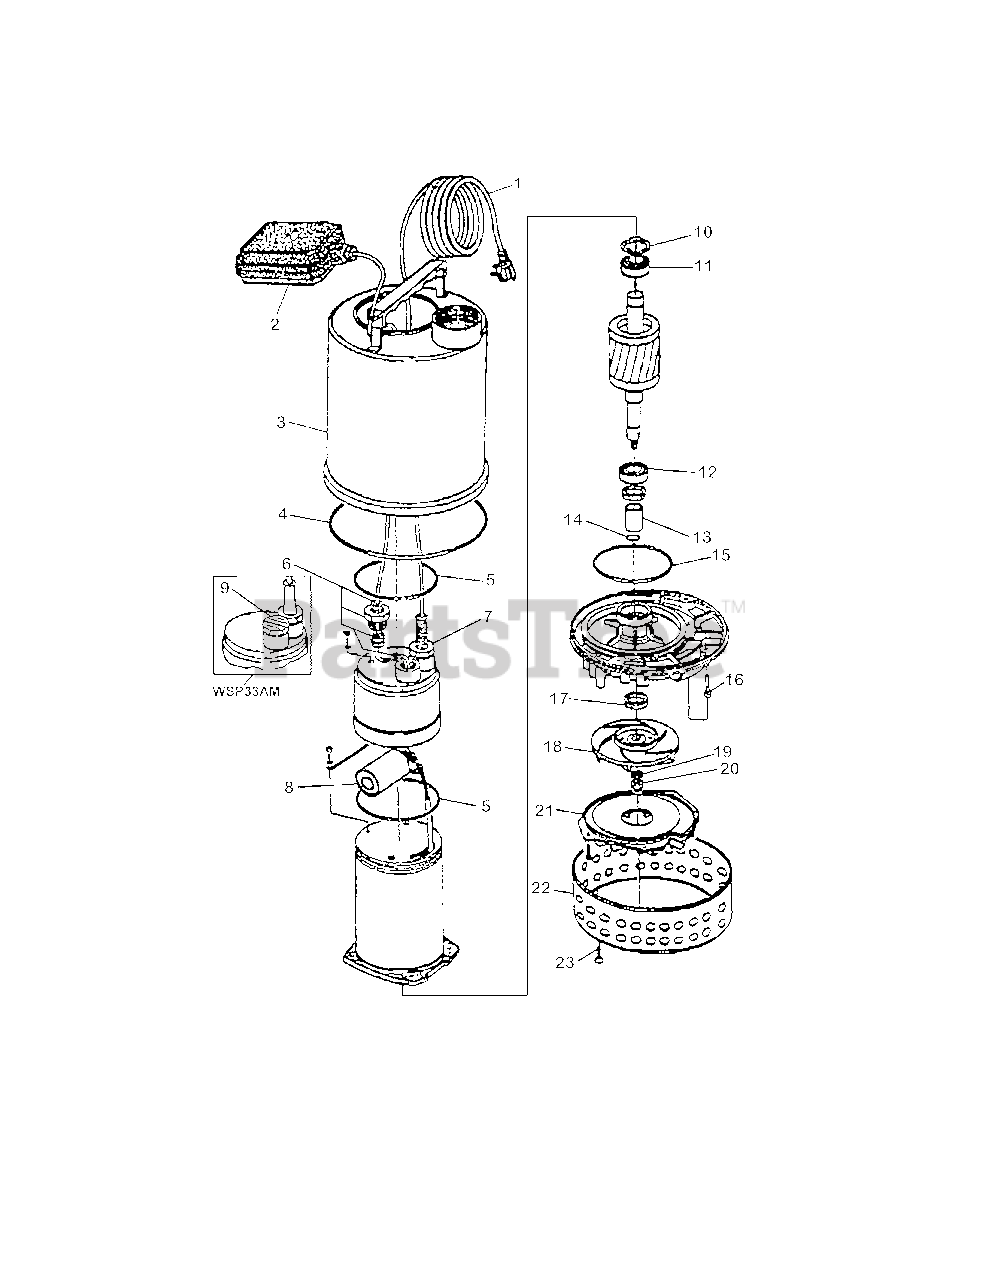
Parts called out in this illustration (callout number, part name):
1	POWER WIRE
3	CASING (NOT AVAILABLE)
4	O-RING (3X154.5)
5	O-RING (2.62X75.87)
7	CONNECTOR, CABLE
8	CAPACITOR (30UF)
10	RING, ADJUSTING
11	BEARING, BALL (6000ZZ)
12	BEARING, BALL (6200ZZ)
13	SLEEVE, SHAFT
14	O-RING (1.78X6.07)
15	O-RING (3.53X85.32)
16	SCREW (5X12)
17	SEAL, LIP
18	IMPELLER
20	NUT, IMPELLER
21	COVER, SUCTION
22	STRAINER
23	SCREW (5X8)
